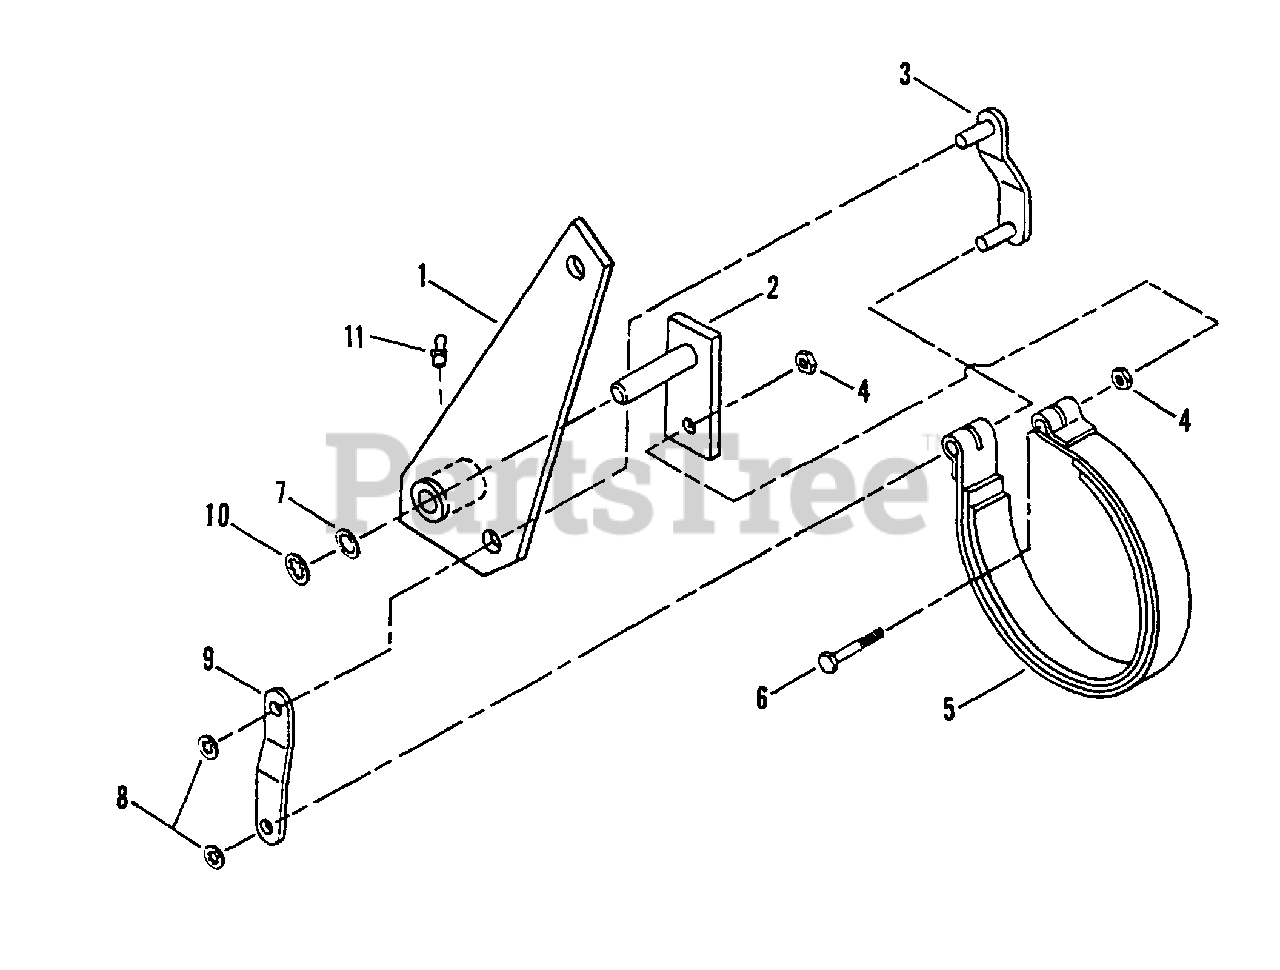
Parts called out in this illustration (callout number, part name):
1	LEVER, Brake (Right Hand)
2	WELDMENT, Brake Stud
3	LINK, Brake
4	NUT, 3/8-16 Hex
5	BAND, Brake, 6"
6	BOLT, 3/8-16 X 2, GD5, CZ
7	BUSHING, Machinery,5/8" I.D. x 1" O.D.
8	RETAINER, 3/8"
9	PLATE, Brake Link
10	RETAINER, 5/8" Bolt
11	LUBE FITTING, 1/4-28 Thread Forming
